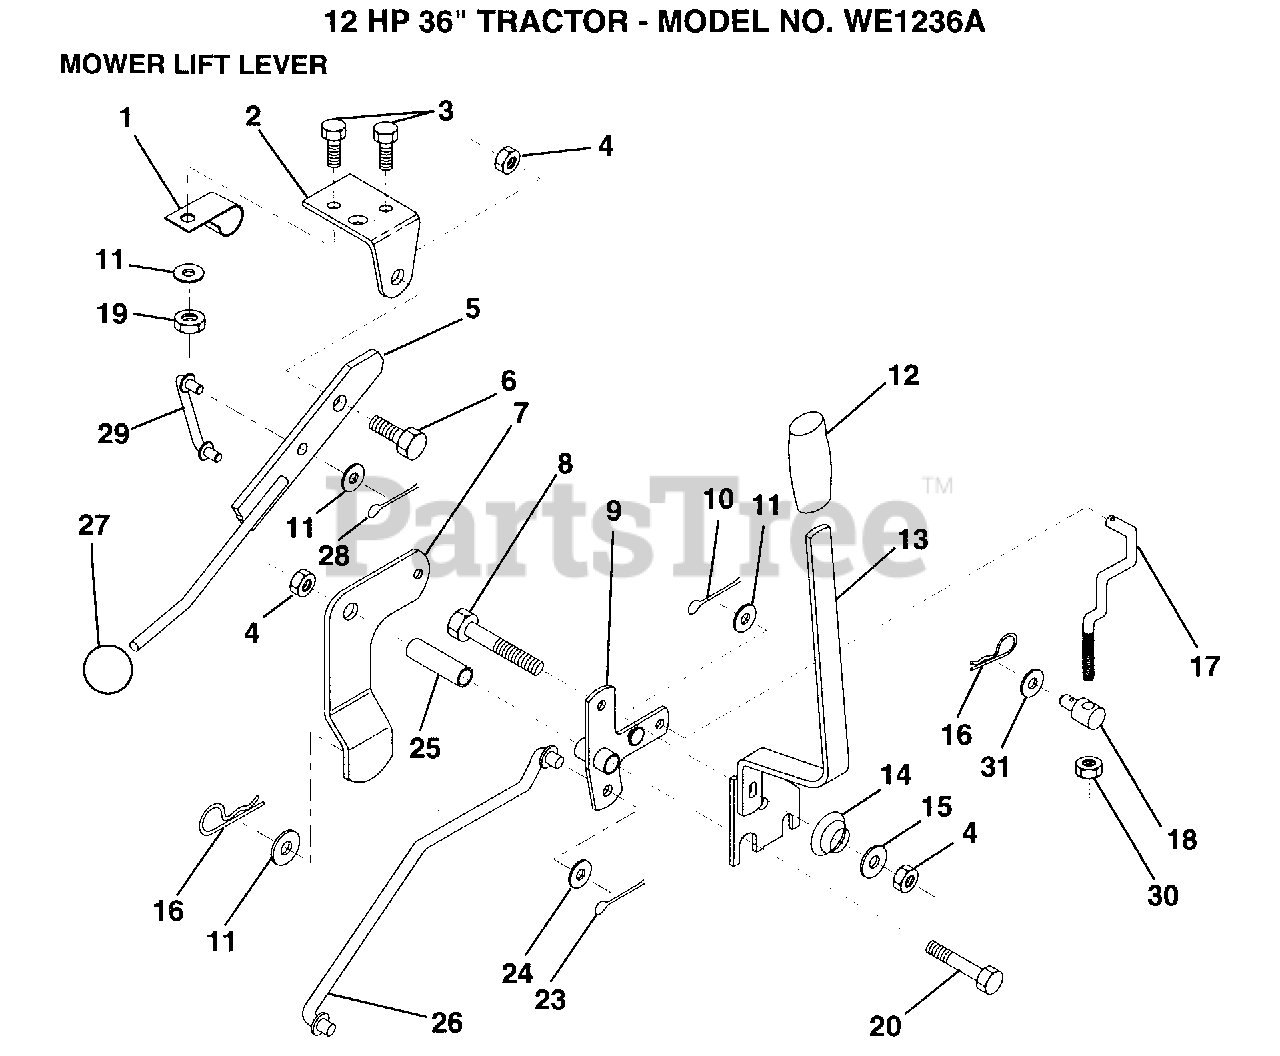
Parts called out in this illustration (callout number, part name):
1	"CLIP,INSULATOR"
2	BRKT CLUTCH
3	BOLT
4	NUT
5	CLUTCH LEVER AS
6	"BOLT, SHOULDER LT"
7	MWR CLUTCH ARM AS
8	BOLT
9	"BELLCRANK,LIFT"
10	COTTER PIN
11	WASHER
13	HANDLE.ASM.LIFT
14	SPRING COMPRESSIO
15	WASHER T
16	SPRING.RETAINER
17	"LINK,LIFT FRT"
18	TRUNION
20	BOLT
23	PIN COTTER 1/8
25	TUBE SPACER
26	ROD LIFT MOWER
27	KNOB T(3/8 HOLE)
29	CLUTCH LINK
30	NUT
31	WASHER
